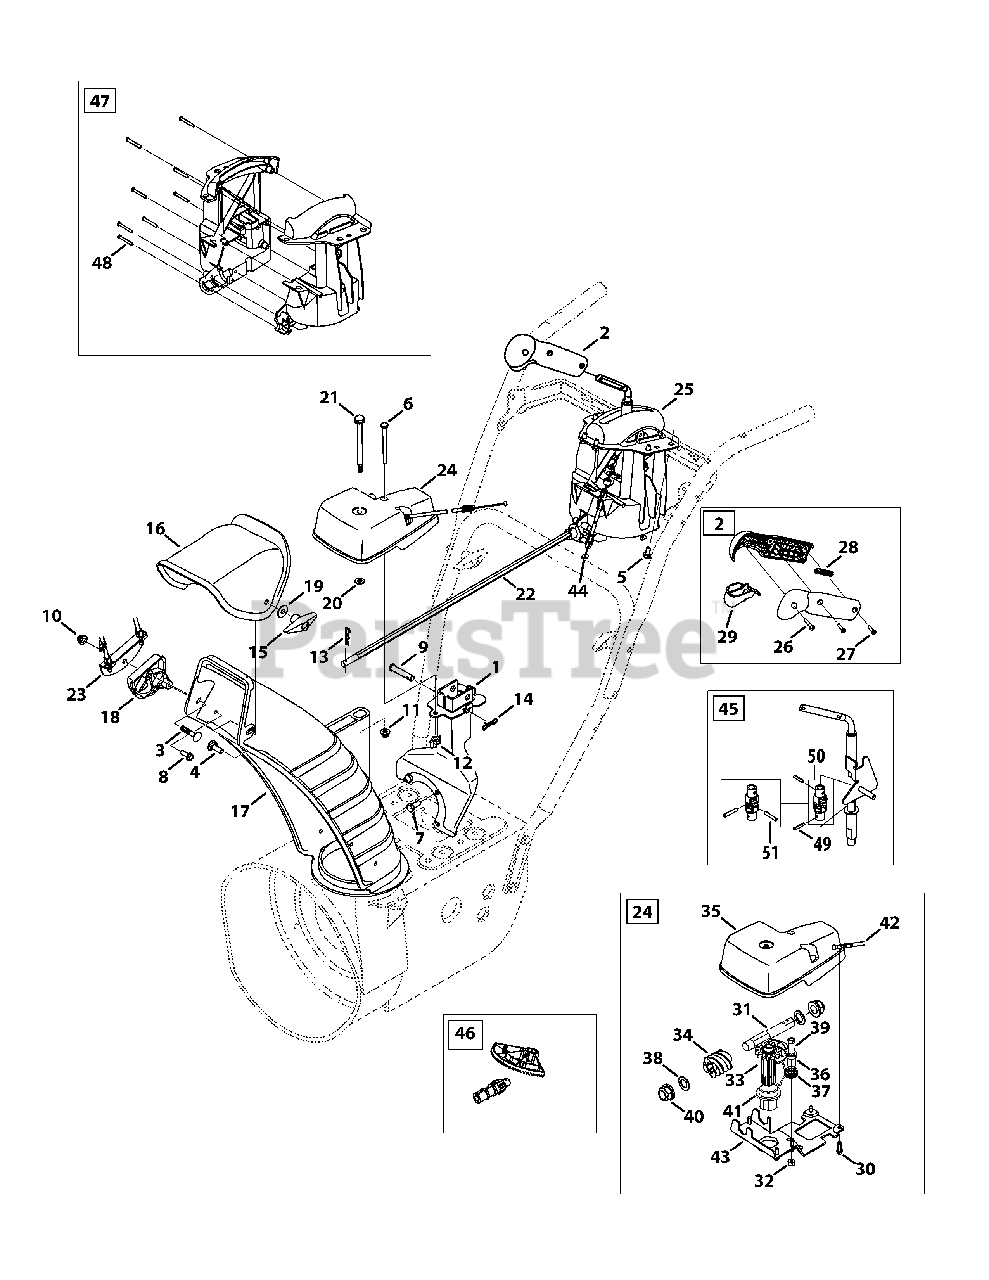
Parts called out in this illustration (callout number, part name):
1	Chute Support Bracket
2	Trigger Housing Assembly
3	Bolt, Carriage, 5/16-18 x 1.50
4	Bolt, Carrier, 5/16-18 x 1.00
5	Screw, HL, 1/4-15 x 0.50
6	Hex Head Screw, 1/4-20 x 3.00
7	Hex Head Screw, 5/16-24 x .750
8	Screw, HL, 1/4-15 x 0.750
9	Clevis Pin, 3/8 x 1.87
10	Nut, Flangelock, 5/16-18
11	Nut, Flangelock, 1/4-20
12	Wing Nut, 1/4-20
13	Internal Cotter Pin
14	Bow-Tie Cotter Pin
15	Wing Knob, 5/16-18
16	Chute, Upper
17	Chute, Lower
18	Cable Guide, Chute Tilt
19	Washer, Flat, .349 x .879
20	Washer, Flat, .25 x .630
21	Screw, Shoulder, .312 x 3.5 x 1/4-20
22	Chute Rod, 3/8 Hex
23	Cable Bracket
24	Gearbox Assembly, Chute Rotation
25	Chute Control, 4-Way
26	Screw, #8 x 1.00
27	Screw, 8-32 x .750
28	Joystick Plug
29	Joystick Trigger
30	Screw, 12-16 x .75
32	Hexlock Nut, 1/4-28
33	Gear, 14 T
34	Worm
35	Gear Cover
37	Torsion Spring, .721 ID x .474
38	Washer, Flat, .625 x 1.0 x .067
39	Screw, Shoulder, .340 x .950 x 1/4-28
40	Hex Bearing
41	Flange Bearing
43	Gear Bracket
44	4-Way Cable
44	Cable Clip
45	Shift Assembly
46	Gear Set Assembly
47	Handle Housing Assembly
48	Screw, #8-18 x 1.250
50	Block, Asm Joint
51	Pin, Roll
